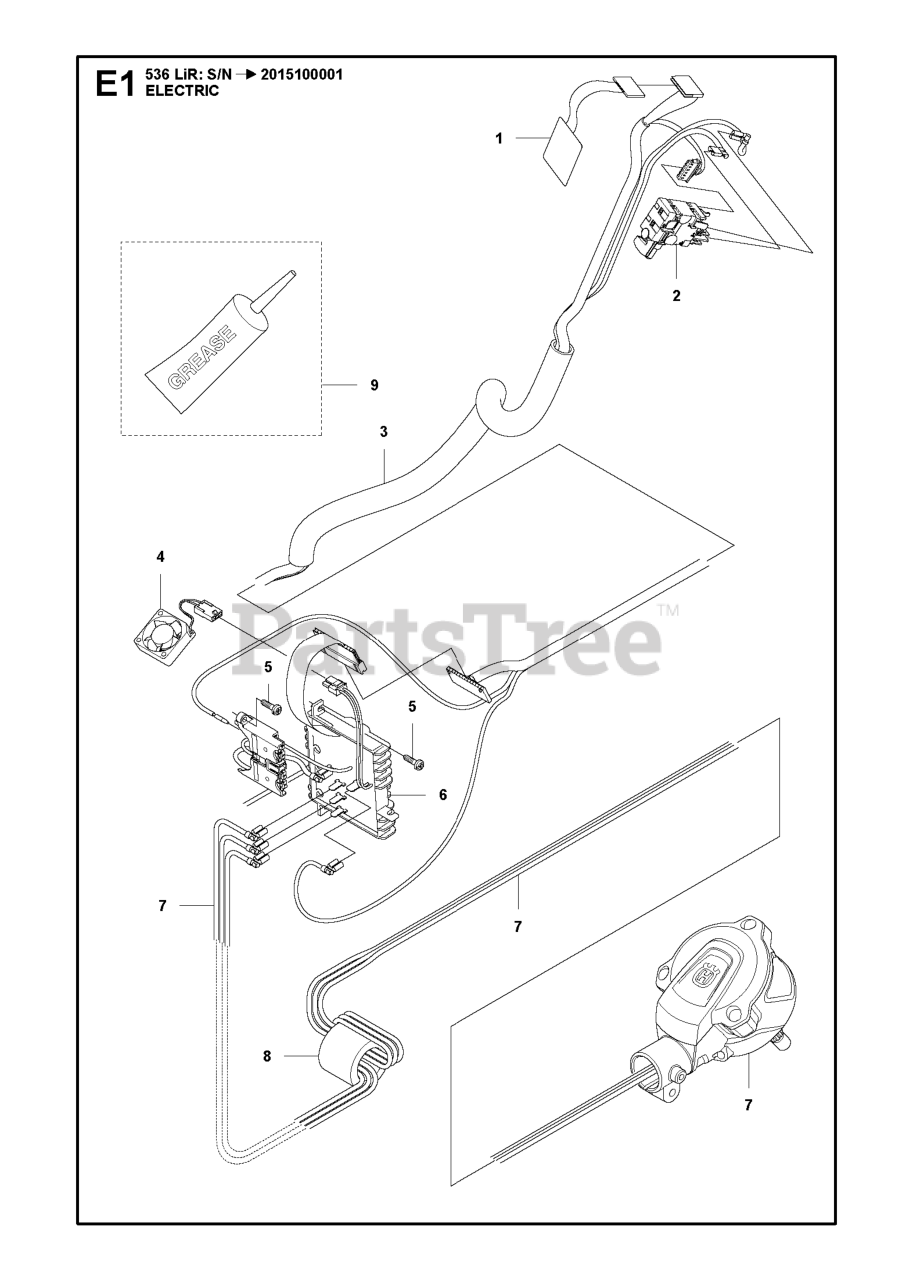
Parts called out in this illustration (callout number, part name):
2	TRIGGER SWITCH
8	FERRITE CORE
9	GREASE TUBE Q8 RUYSDAEL WR2
